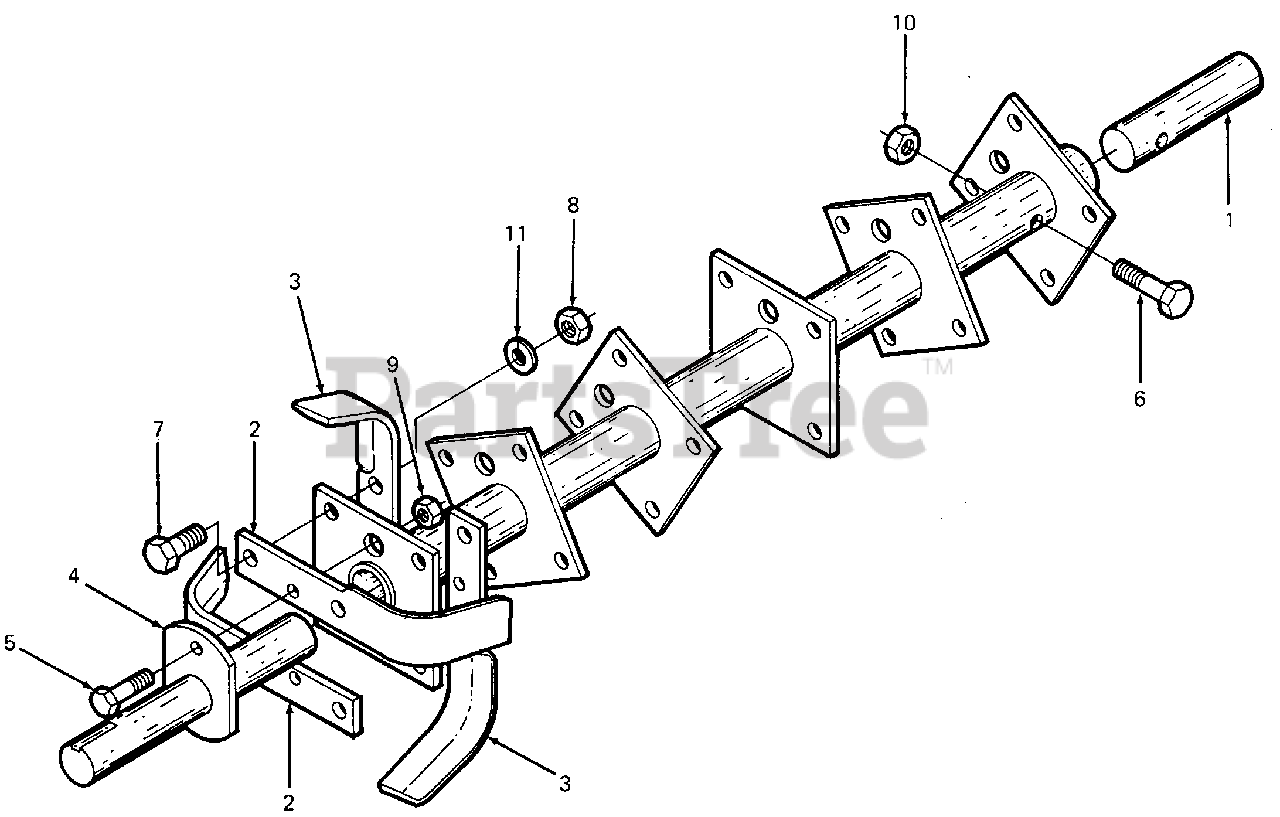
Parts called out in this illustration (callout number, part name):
1	Shaft, Stub LH
4	Shaft, Stub RH
5	Screw, Hex Cap, 5/16-18 X 1-1/2 Lg GR 5
6	Screw, Hex Cap, 3/8-16 X 2-1/4 Lg GR 5
7	Screw, Hex Cap, 7/16-14 X 1-1/2 Lg GR 5
8	Nut, Hex, 7/16-14, GR 5
9	Nut, Hex Lock, 5/16-18
10	Nut, Hex Lock, 3/8-16
11	Washer, Lock, 7/16
